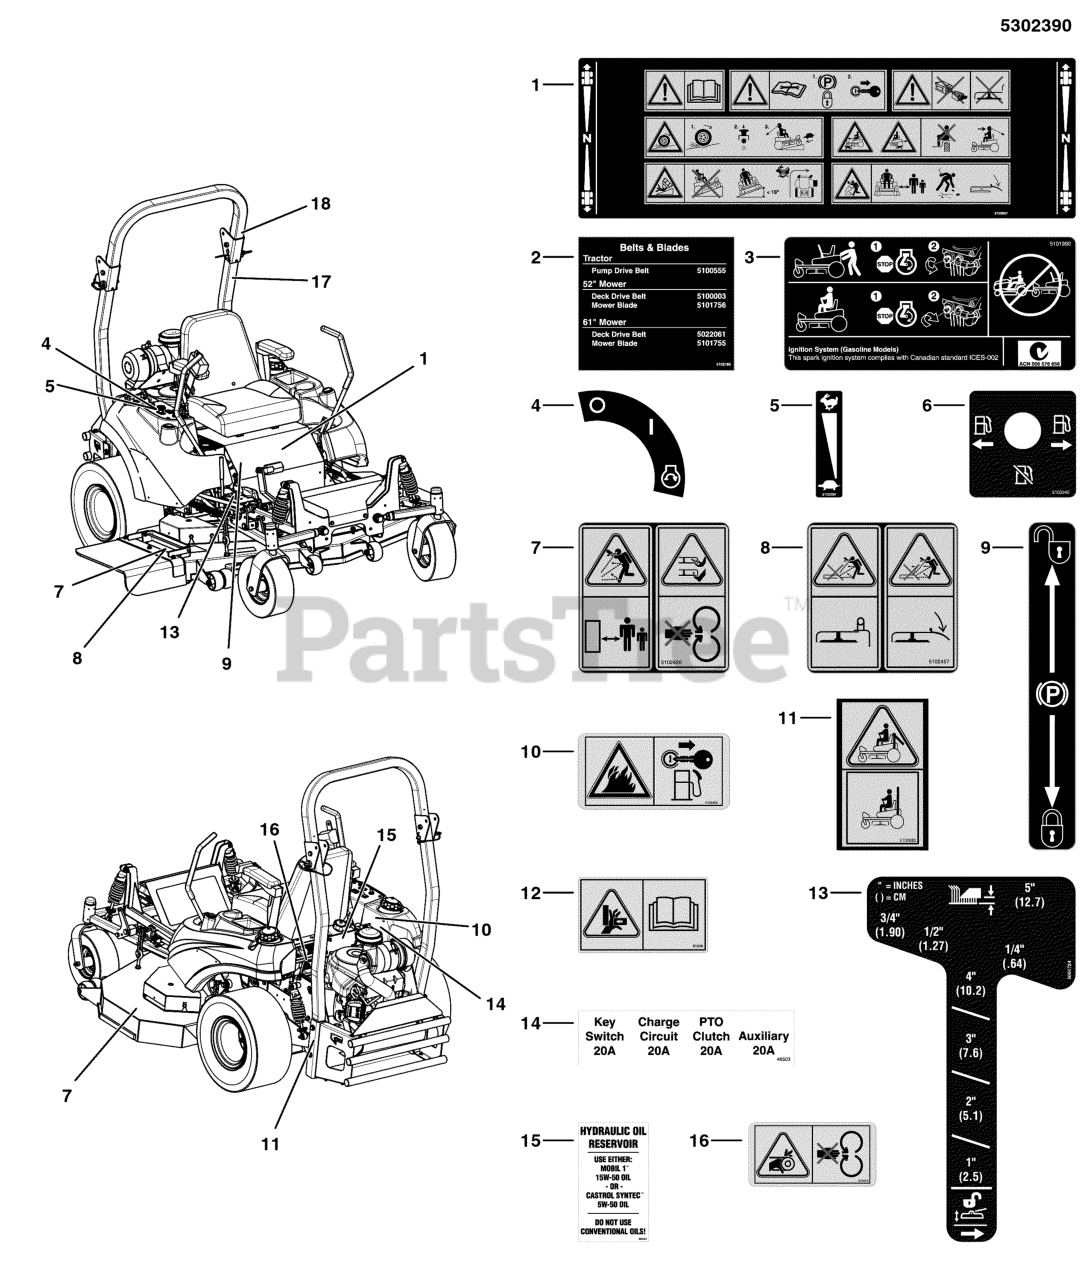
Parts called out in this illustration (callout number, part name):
1	DECAL, MAIN SAFETY, ANSI CE
2	DECAL, BELT AND BLADE, IS2000Z
3	DECAL, CZT HYRDO RELEASE
4	DECAL, IGNITION SWITCH
5	DECAL, THROTTLE CONTROL
6	DECAL, FUEL VALVE
7	DECAL, DANGER, MOWER DECK, ANSI EXP
8	DECAL, DANGER DISCHARGE ANSI EXPORT
9	DECAL, PARKING BRAKE SYMBOLS
10	DECAL, FIRE ANSI EXPORT
11	DECAL, WARNING, ROLL BAR, CE
12	DECAL, PINCH POINT, CE
13	DECAL, HEIGHT CITATION
13	DECAL, CUT HEIGHT
14	DECAL, FUSE LOCATION
15	DECAL, OIL RESEVOIR
16	DECAL, CE DANGER
